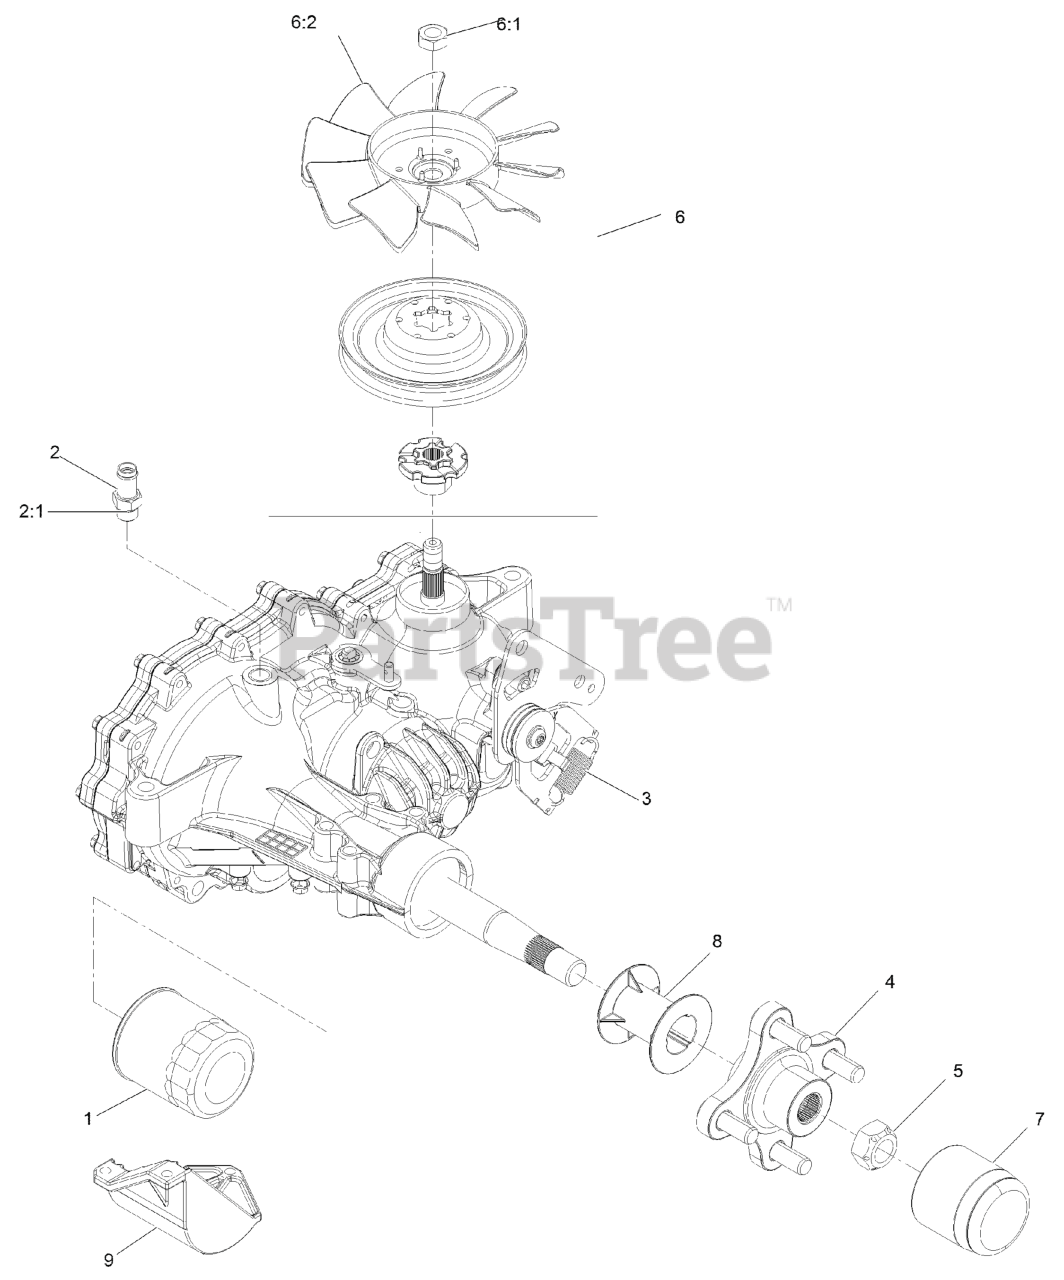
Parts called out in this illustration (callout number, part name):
1	ELEMENT-OIL FILTER, HYD
2	ADAPTER-STRAIGHT
2:1	O-RING
3	SPRING-EXTENSION
4	HUB-OFFSET
5	NUT-HUB
6	Fan And Pulley Kit
7	CAP-AXLE, LONG
8	TUBE-AXLE
9	GUARD-FILTER, RH
